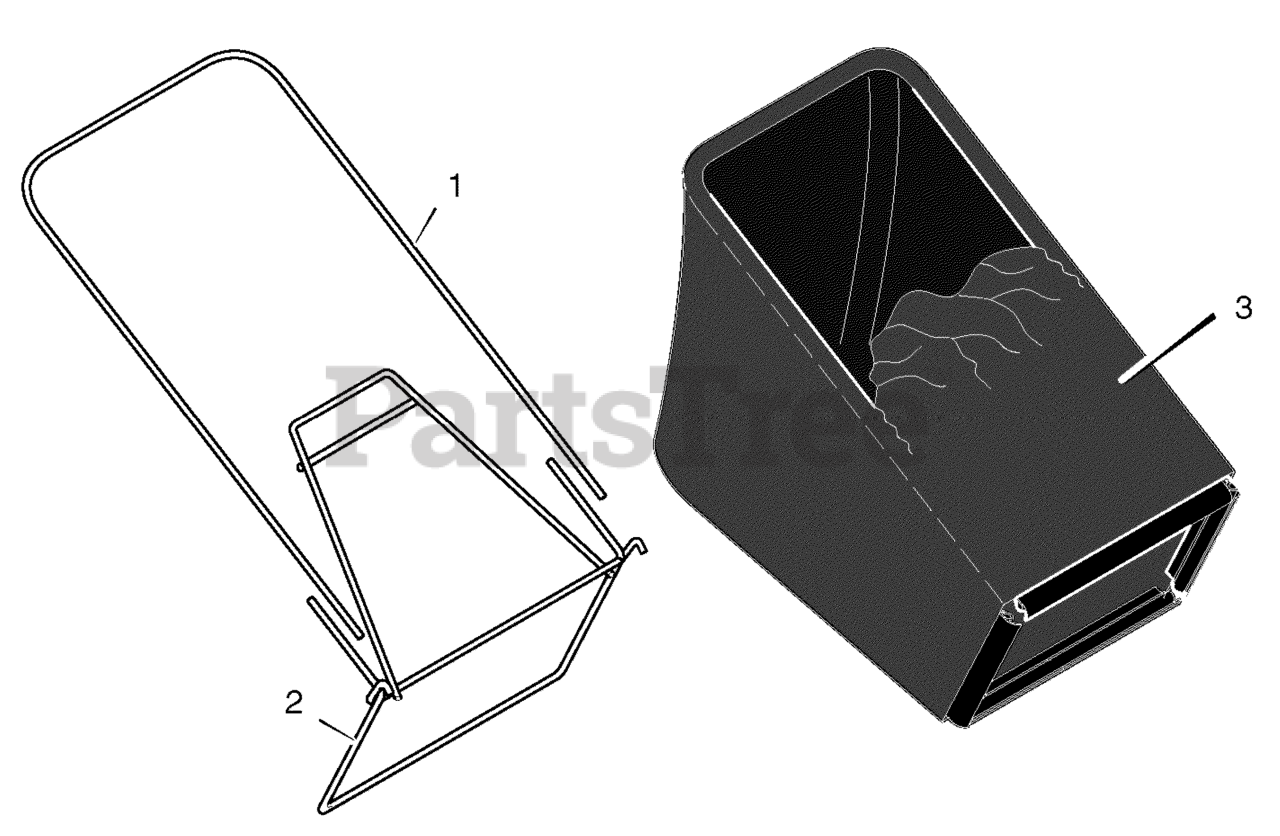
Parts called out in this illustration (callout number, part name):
1	Frame, Top
2	Frame Assembly
3	Bag, Cloth Black
